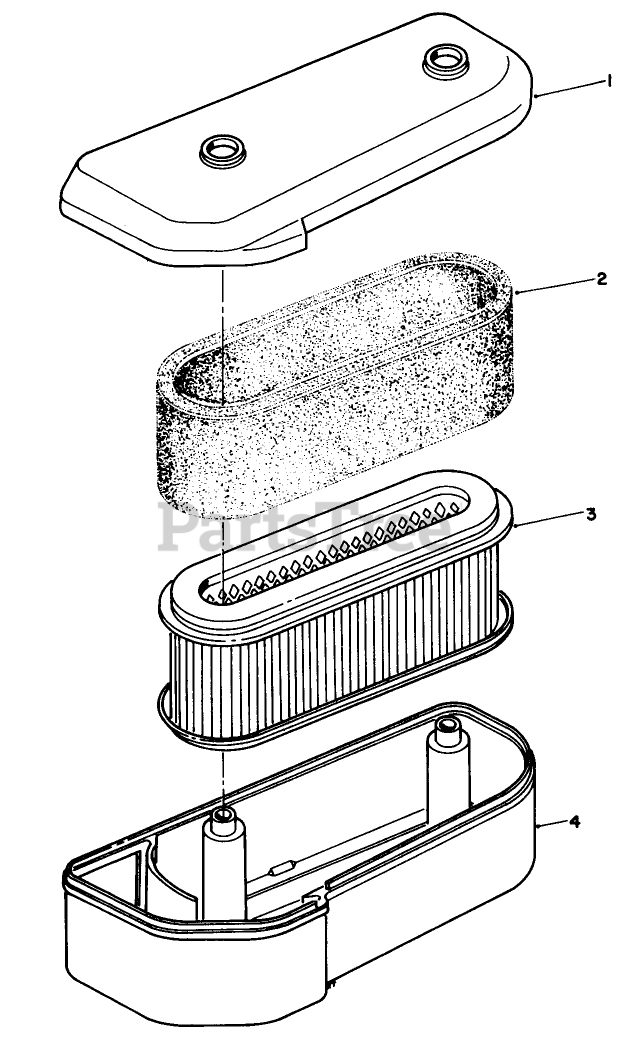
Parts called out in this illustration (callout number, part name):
1	CAP-Air Filter
2	Element
3	Element
4	CASE-Air Filter
